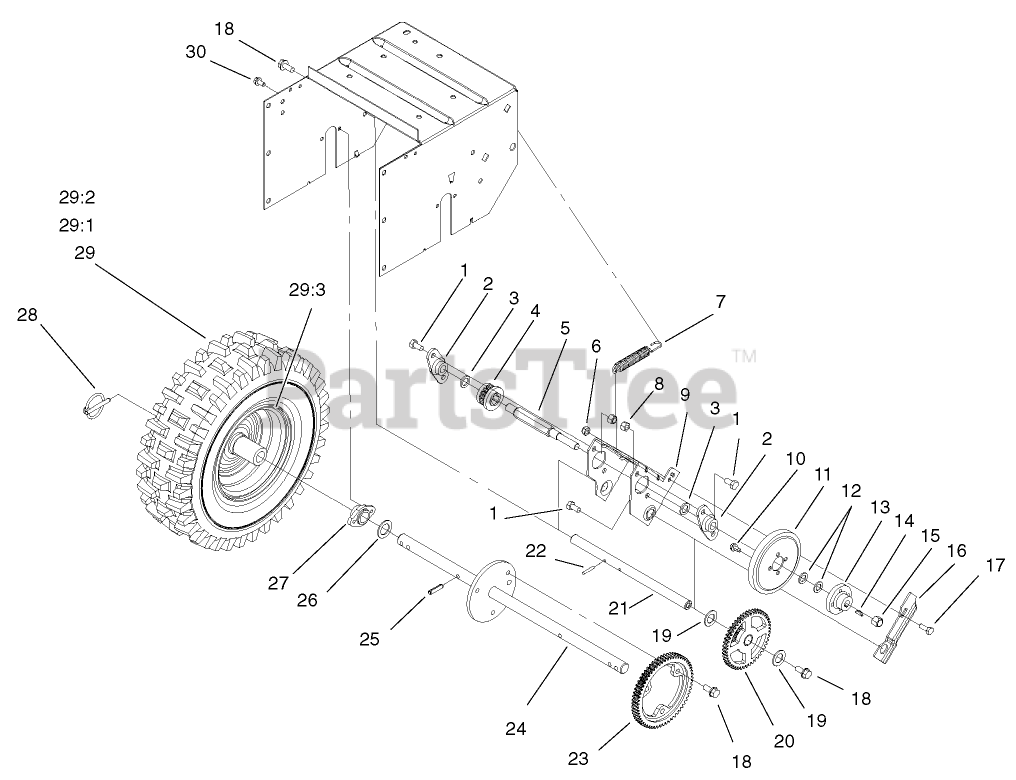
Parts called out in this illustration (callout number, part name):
1	SCREW-HH
2	BEARING-WHEEL, FRICTION
3	WASHER-FLAT
4	PINION
5	SHAFT-WHEEL, FRICTION
6	NUT-LOCK, NI
7	SPRING-TRACTION
8	NUT-LOCK, NI
9	BRACKET-SLIDING
10	SCREW
11	WHEEL-FRICTION
12	WASHER-THRUST
13	HUB-WHEEL, FRICTION
14	KEY-WOODRUFF
15	NUT-LOCK, NI
16	CAM-RECEIVER
17	SCREW-HH
18	SCREW-HWHTF
19	WASHER-SPECIAL
20	INTERNAL GEAR AND BUSHING ASM
21	SHAFT-PIVOT
22	PIN-SPRING
23	GEAR-AXLE
24	SHAFT-AXLE
25	PIN-SPRING
26	WASHER-THRUST
27	BEARING-AXLE
28	PIN-LYNCH
29	ORDER SEPERATE COMPONENTS
29:2	TUBE-INNER
29:3	RIM-WHEEL
30	SCREW-HWH
